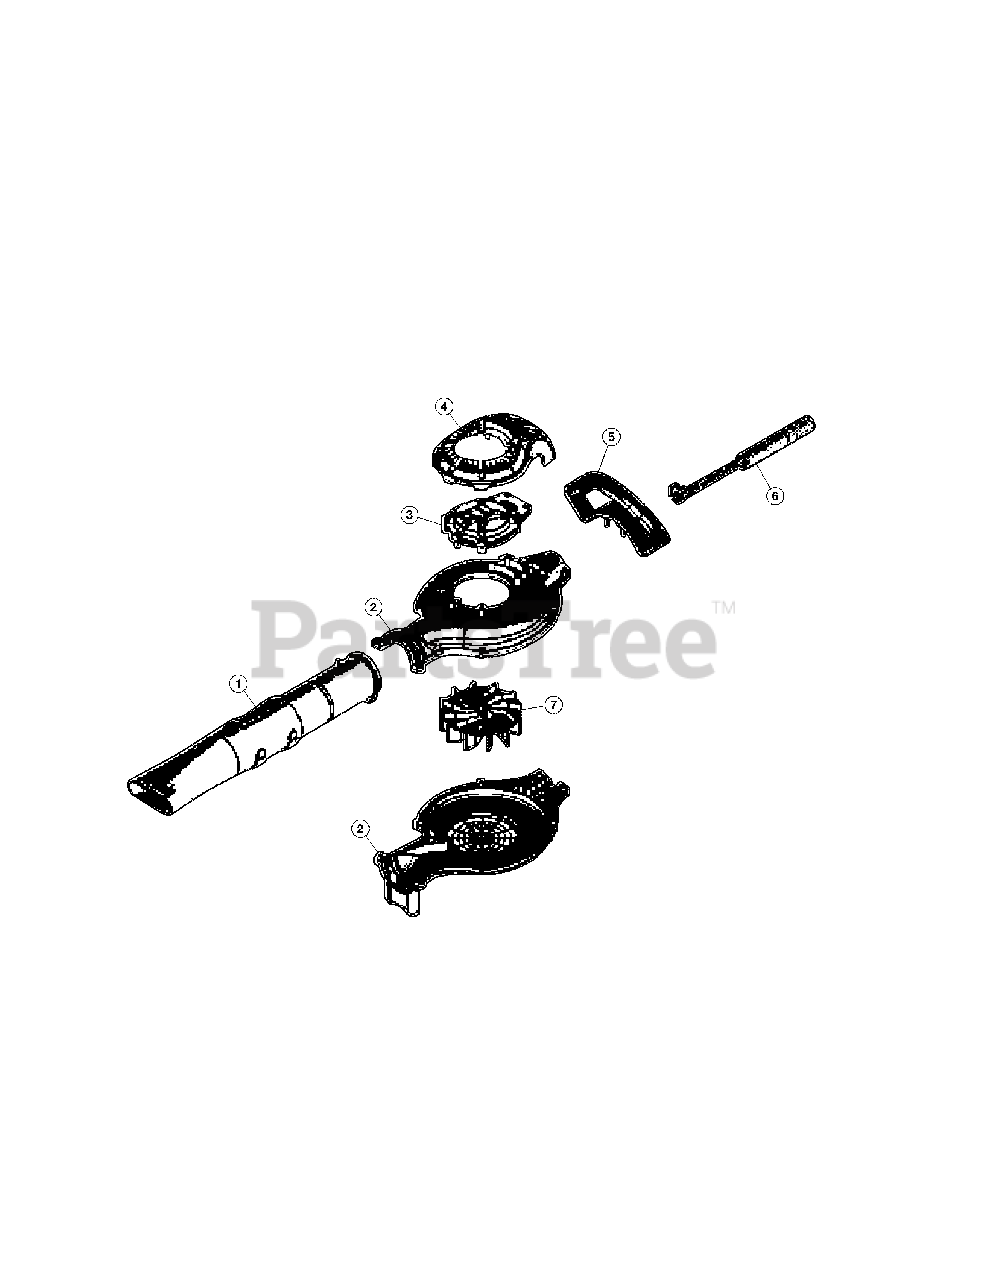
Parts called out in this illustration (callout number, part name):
1	Blower Tube Assembly
2	Blower Housing Assembly
3	Blower Motor Assembly
4	Blower Cover Assembly
5	Assist Handle Assembly
6	Power Lok Blower Tube Cable Assembly
7	Blower Impeller Assembly
